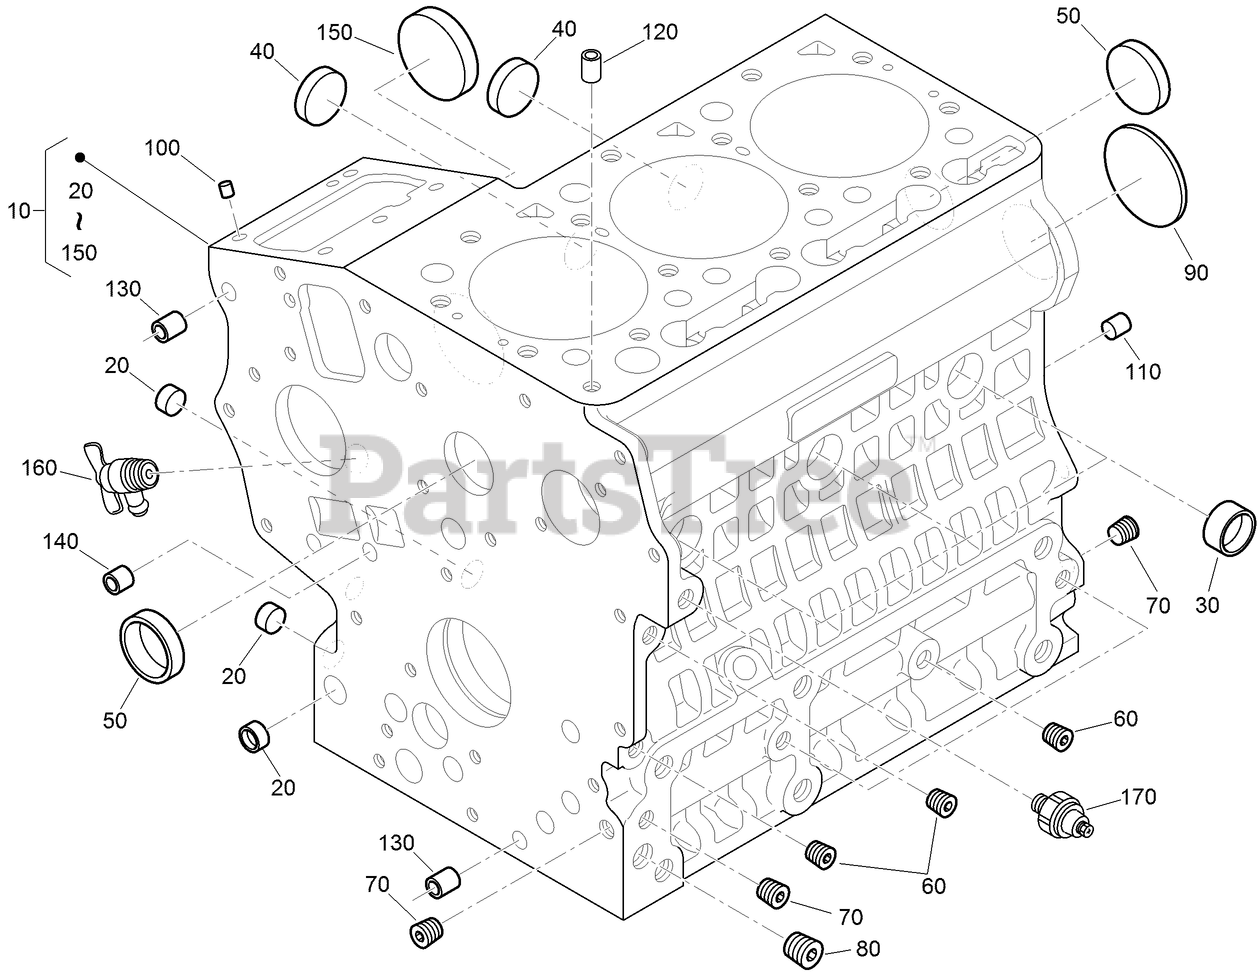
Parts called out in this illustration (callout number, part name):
10	CRANKCASE ASM
20	CAP-SEALING
30	CAP-SEALING
40	CAP-SEALING
50	CAP-SEALING
90	PLUG-EXPANSION
100	PIN-STRAIGHT
110	PIN-STRAIGHT
120	PIN-PIPE
130	PIN-PIPE
140	PIN-PIPE
150	COVER-FUEL, CAMSHAFT
160	DRAINCOCK ASM
170	SWITCH-OIL
